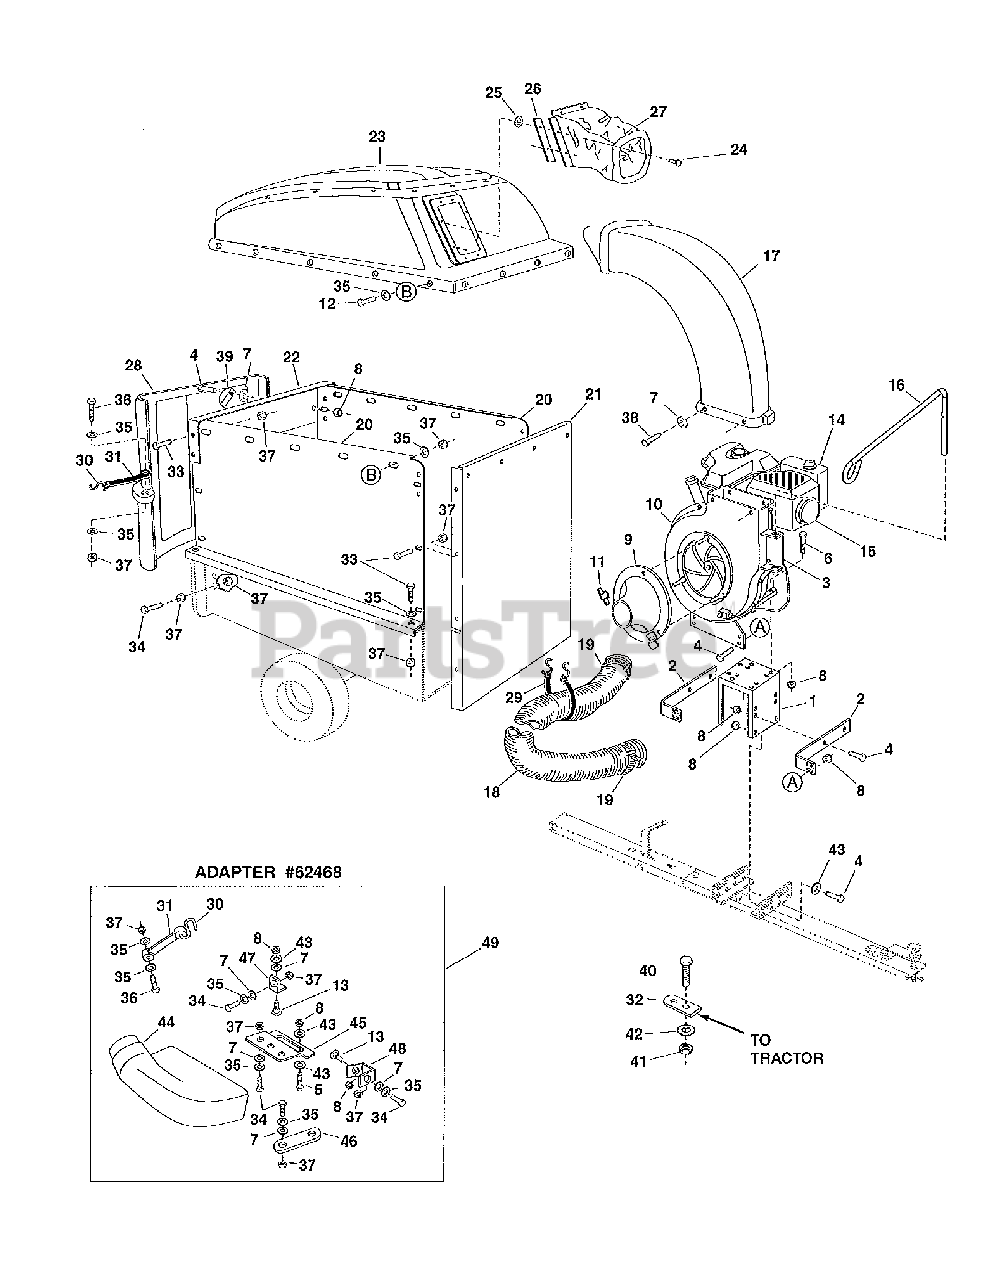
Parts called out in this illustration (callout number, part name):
1	Engine Base
2	Brace, Housing
3	Hose Hanger Bracket Ass'y.
4	Bolt, Hex 5/16-18 x 3/4"
5	Bolt, Hex5/16-18 x 1-1/4"
6	Bolt, Hex5/16-18 x 1-1/2"
7	Washer, Nylon 21/64"
8	Nut, Hex Nylock 5/16-18
9	Hose Adapter
10	Impeller Housing Assembly
11	Knob (See Item #8, Page 22)
12	Bolt, Hex 1/4-20 x 3/4"
13	Bolt, Carr. 5/16" x 3/4"
14	Engine (49 State)
14	Engine (California)
15	Deflector, Muffler
16	Hose Hanger Rod
18	Hose (6" x 84")
19	Hose Clamp 6"
23	Hard Top Assembly
24	Rivet, 3/16"
25	Washer, Flat 3/16"
26	Boot Mounting Strap
27	Hard top Boot
28	Poly Rear Door
29	Strap, Tarp 25" "S"
30	Hook, #32
31	Strap, Tarp (Less Hooks)
32	Hitch Plate
33	Bolt, Hex 1/4-20 x 5/8"
34	Bolt, Hex 1/4-20 x 1"
35	Washer, 1/4" STD
36	Bolt, Hex 1/4-20 x 1-1/4"
37	Nut, Hex Nylock 1/4-20
38	Screw, SelfTap 5/16-18 x 3/4"
39	Door Latch
40	Bolt, Hex 1/2-13 x 1-1/4"
41	Nut, Hex Nylock 1/2-13
42	Washer, Flat 7/16"
43	Washer, 5/16" STD
44	Adapter, Deck
45	Bracket, Deck Adapter
46	Mounting Strap
47	Angle Bracket
48	Mounting Bracket
49	Deck Adapter Kit
